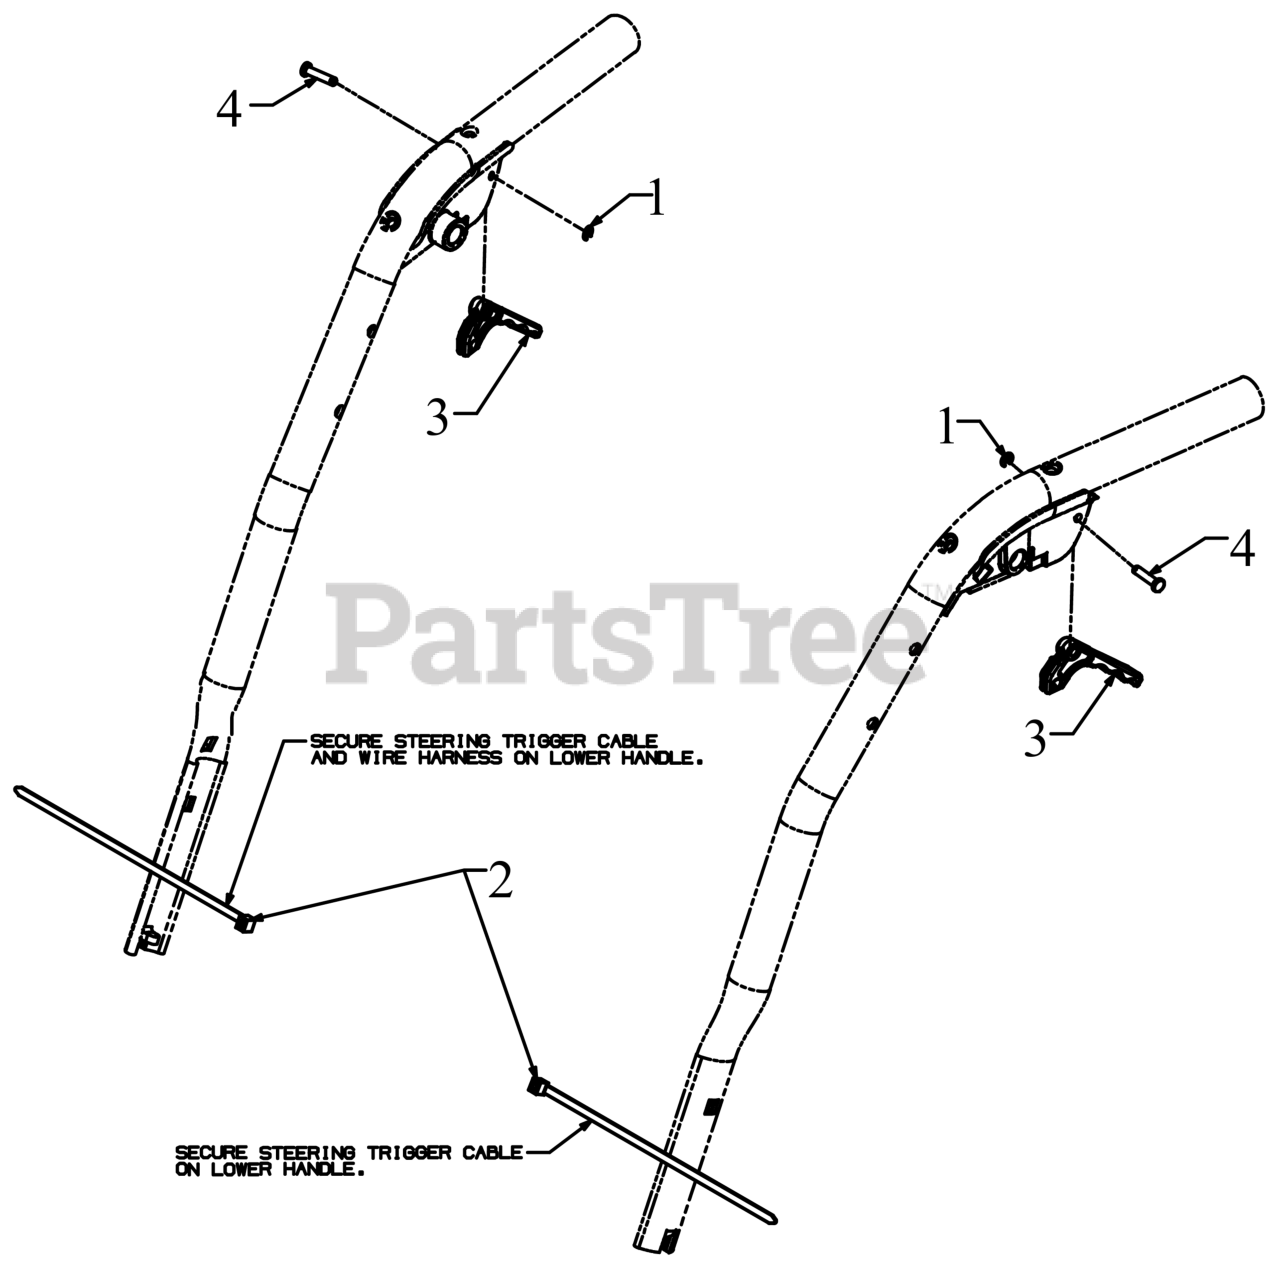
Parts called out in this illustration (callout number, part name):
1	E-RING
2	7" CABLE TIE
3	TRIGGER CLUTCH LOCK
4	STEERING TRIGGER PIN 3/16
